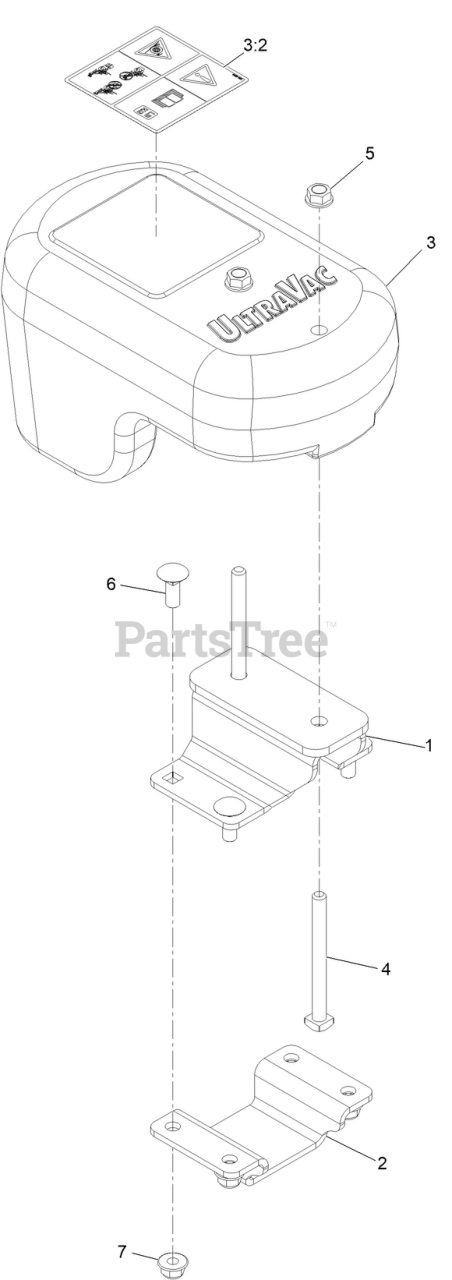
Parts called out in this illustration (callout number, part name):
1	WELD-CASTER WEIGHT BRACKET
2	BRACKET-CASTER WEIGHT BTM
3	ASM-Weight W/ Decal, 70 Lb
3:2	DECAL-WARNING, TRACTION
4	BOLT, SQUARE HEAD YZ
5	NUT-HHF, WHIZ
6	BOLT-CARR
7	NUT-HF, NI
